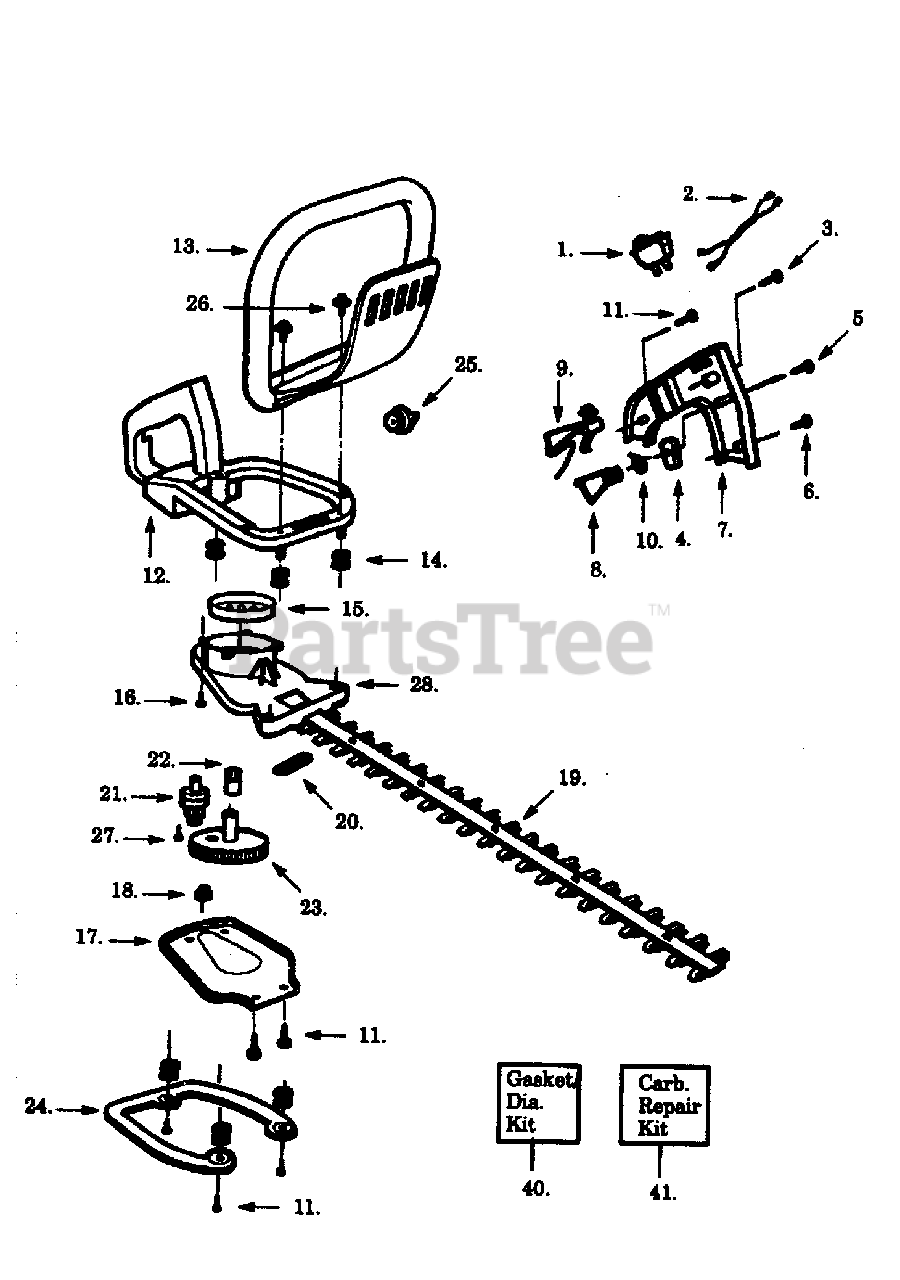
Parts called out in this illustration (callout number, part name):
2	LEAD
3	SCREW 8-16 X 9/16 (PLAS
6	SCREW-10-16 X 1-3/8 PLA
8	TRIGGER
9	THROTTLE LOCK
12	REPL BY 530 04 78-79
14	ANTIVIBE MOUNT
15	CLUTCH DRUM
17	PLATE-GEARBOX COVER
18	BLADE BUSHING
19	BLADE ASSY
24	ISOLATOR PLATE
25	COVER
27	SCREW-10-14 X 13/16 (PL
28	GEARBOX ASSY
29	METERING DIAPHRAGM
32	PUMP DIAPHRAGM
33	FULCRUM PIN
35	SCREEN-DUTCH TWILL INLE
36	VALVE/INLET.
39	WELCH PLUG
40	REPL BY 530 06 98-44
43	LIMITER CAP (LOW-BLUE)
5300353-12	CARBURETOR KIT
5300696-56	REPAIR KIT
